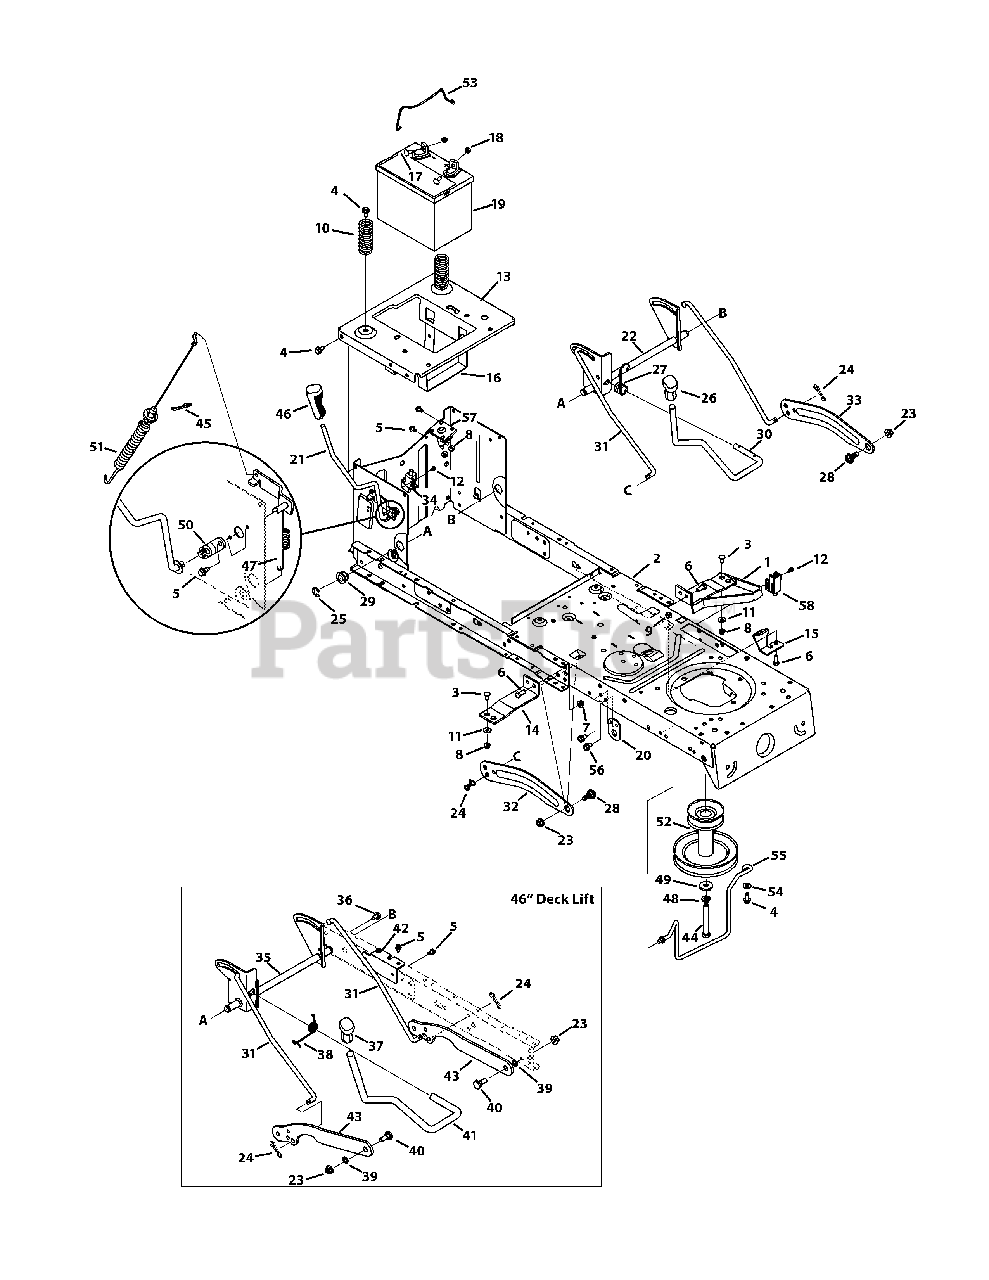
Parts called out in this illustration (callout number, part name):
1	Support Bracket - Powder Black
1	Support Bracket - Black Jack
2	Frame Assembly - Powder Black
2	Frame Assembly - Black Jack
3	Screw Carriage, 1/4-20 x .62
4	Screw 5/16-18 x .750
5	Screw, 1/4-20 x .500
6	Hex Screw, 5/16-18 x .75
7	Flangelock Nut, 5/16-18
8	Flangelock Nut, 1/4-20
9	Hexlock Nut, 5/16-18
10	Compression Spacer, 1.28 x 3.125
11	Flat Washer, .28 x .74 x .063
12	Shoulder Spacer, 10-32 x .500
13	Seat Frame Bracket - Powder Black
13	Seat Frame Bracket - Black Jack
14	Running Board Bracket
15	Support Frame Bracket
16	Battery Bracket
17	Hex Head Flange, 1/4-20 x .75
18	Sems Nut, 1/4-20
19	230 CCA Battery
20	Support Bracket
21	PTO Handle Assembly
22	Lift Assembly, 38/42"
23	Flangelock Nut, 3/8-16
24	Bow-tie Cotter Pin
25	E Ring
26	Handle Grip, 1/2
27	Torsion Spring
28	Shoulder Bolt, 3/8-16 x .625 x .175
29	Hex Flange Bearing
30	Deck Lift Handle 38"
30	Deck Lift Handle 42"
31	Lift Rod
32	38/42" Lift Arm, RH - Powder Black
32	38/42" Lift Arm, RH - Black Jack
33	38/42" Lift Arm, LH - Powder Black
33	38/42" Lift Arm, LH - Black Jack
34	Switch Interlock
35	Lift Assembly, 46"
36	Screw, 5/16-18 x .625
37	Handle Grip, 5/8
38	Torsion Spring Handle, 46"
39	Flat Washer, .385 x .62 x .063
40	Shoulder Bolt, 3/8-16 x .500 x .270
41	46" Lift Handle
42	Frame Brace Bracket
43	Lift Deck Link
44	Hex Screw, 7/16-20 x 2.75, 46"
44	Hex Screw, 7/16-20 x 3.25, 38/42"
45	Click Pin, .092 x 1.64
46	Handle Grip, 3/8
47	PTO Spring Extension
48	Regular Duty Washer Lock, 7/16
49	Flat Washer, .450 x 1.250 x .164
50	PTO Bearing
51	Deck Engage Cable
52	Engine Pulley, 3.39 x 6.12, 46"
52	Engine Pulley, 3.39 x 6.12, 38/42"
53	Battery Hold Down Rod
54	Flat Washer, .406 x .875 x .059
55	38" Belt Keeper
55	42" Belt Keeper
55	46" Belt Keeper
56	Screw, 5/16-18.0 x .625
57	12V Solenoid
58	Screw Mount Interlock Switch
